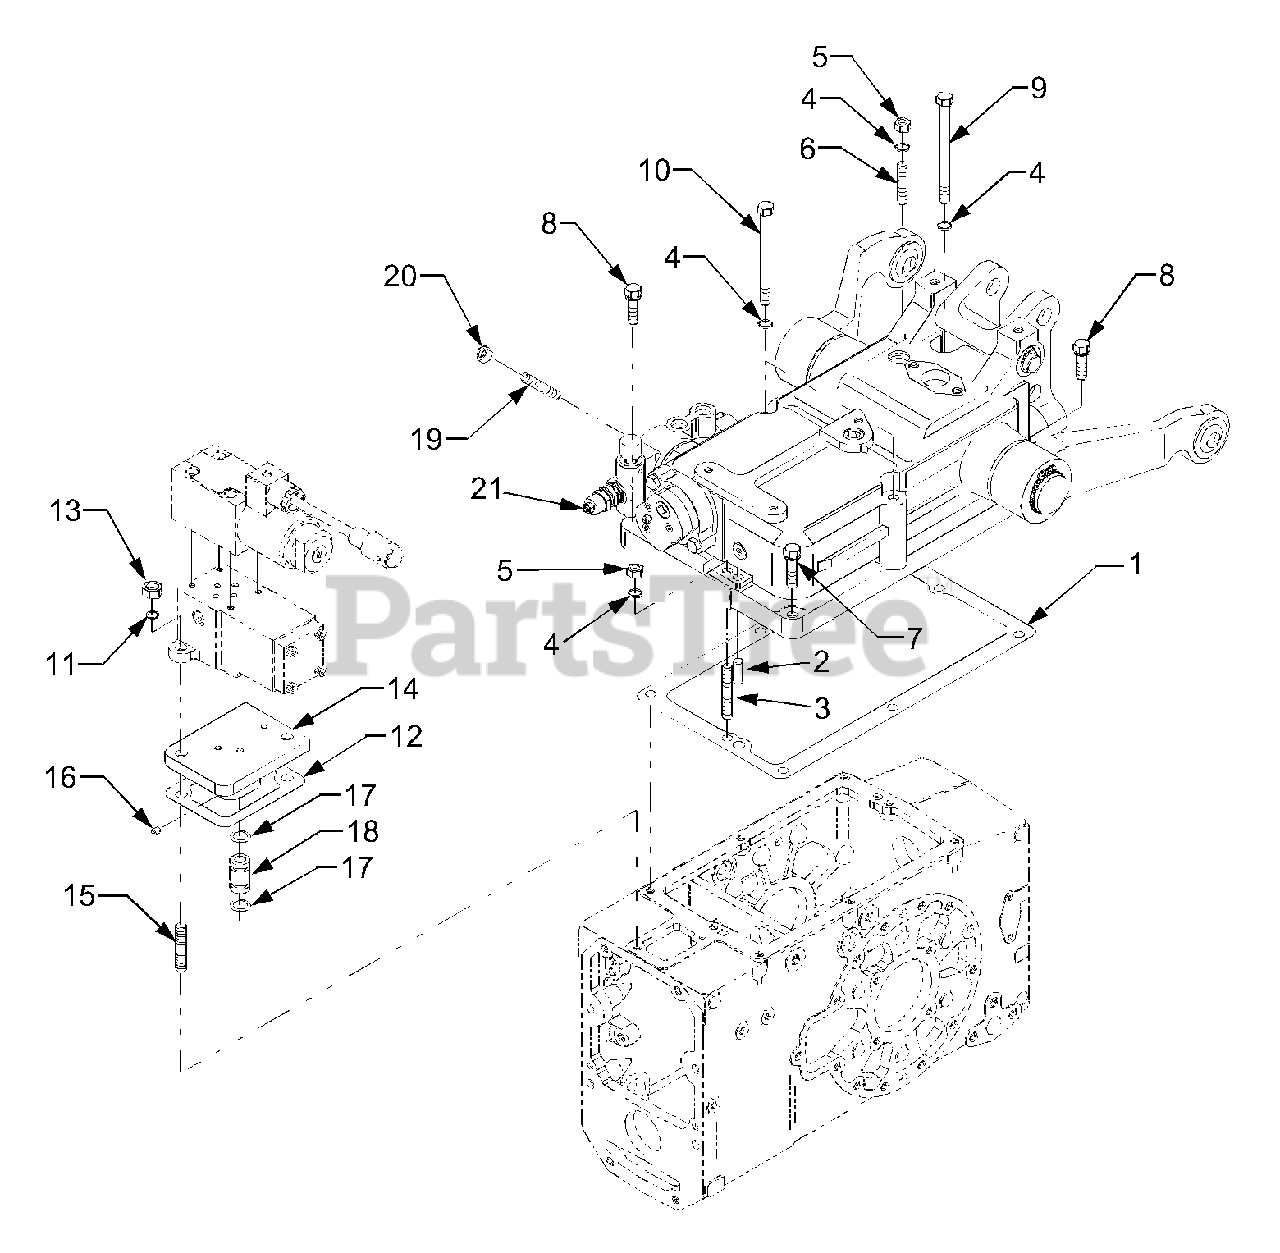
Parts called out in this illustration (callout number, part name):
4	Washer, Spring
11	Washer, Spring
14	Support, Valve
18	Pipe, Connecting
21	Detent Double Ass'y
